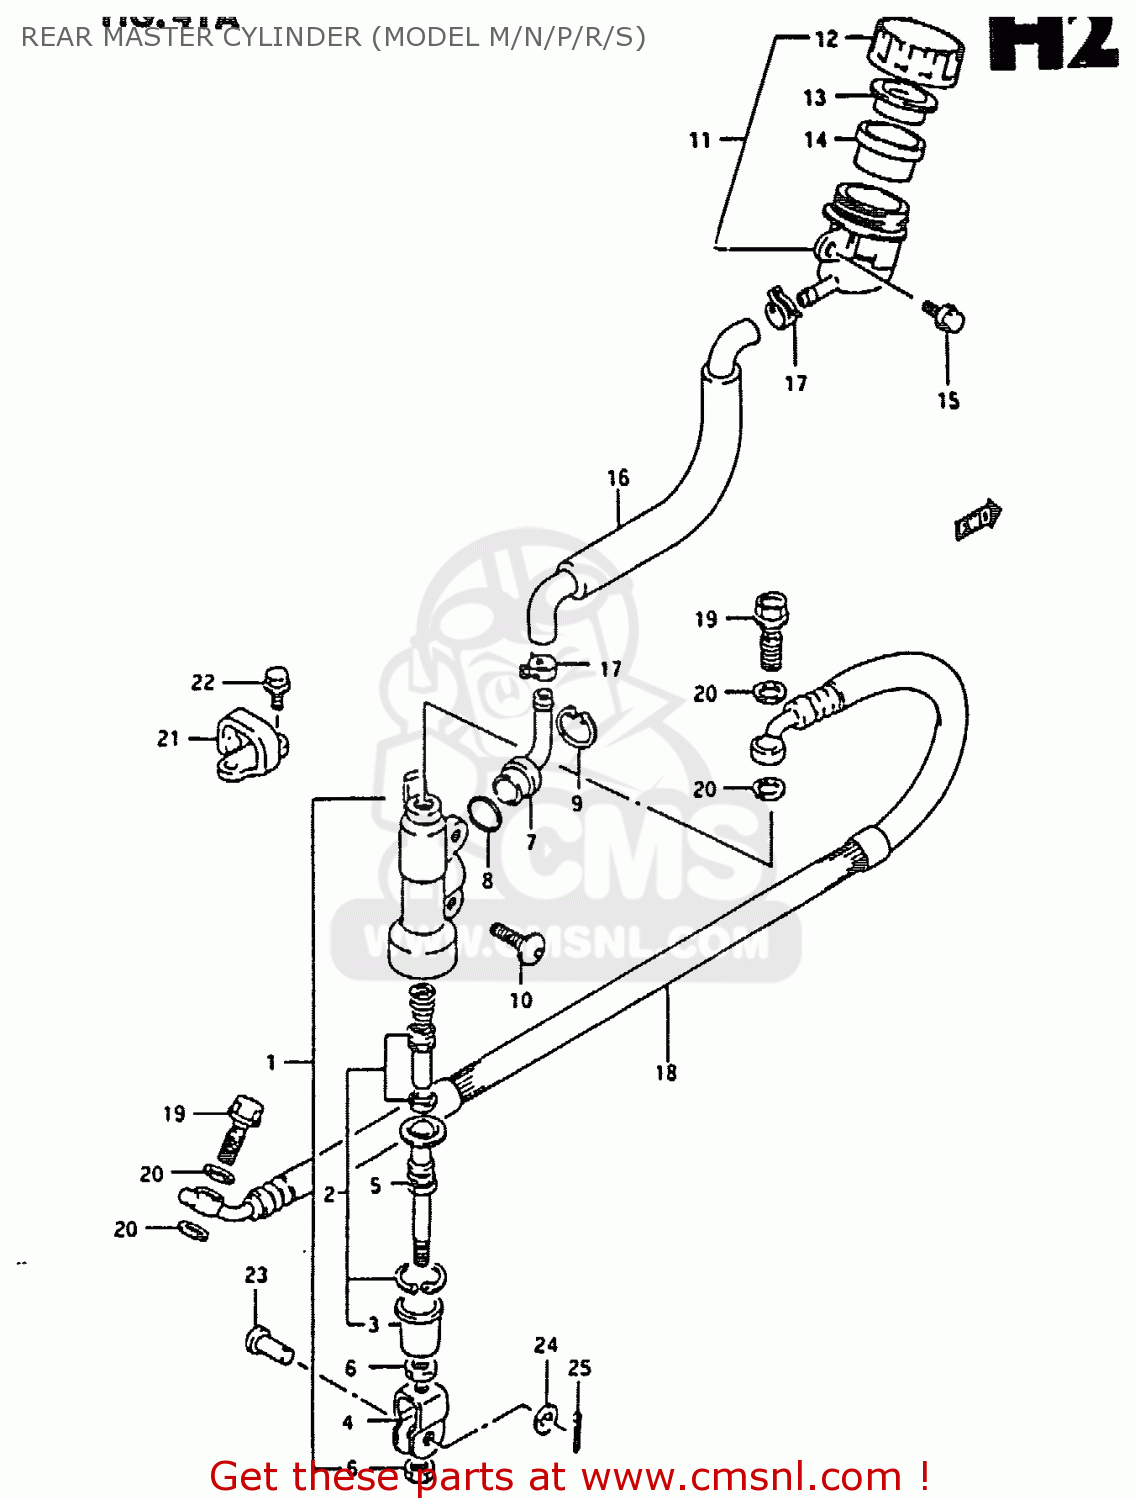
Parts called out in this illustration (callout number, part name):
1	CYLINDER ASSY,RR MASTER
2	PISTON/CUP SET
3	BOOT
4	YOKE
5	ROD,PUSH
6	NUT
7	CONNECTOR
8	O RING
9	CIRCLIP
10	SCREW(6X16)
11	TANK ASSY, RESERVOIR
12	CAP
13	PLATE
14	DIAPHRAGM
15	BOLT
16	HOSE,RESERVOIR TANK
17	CLAMP,RESERVOIR HOSE
18	HOSE,RR BRAKE
19	BOLT UNION
20	WASHER(10X15X1.5)
21	GUIDE,RR BRAKE HOSE
22	SCREW
23	PIN(8X20)
24	WASHER(8.5X13X1.6)
25	PIN
